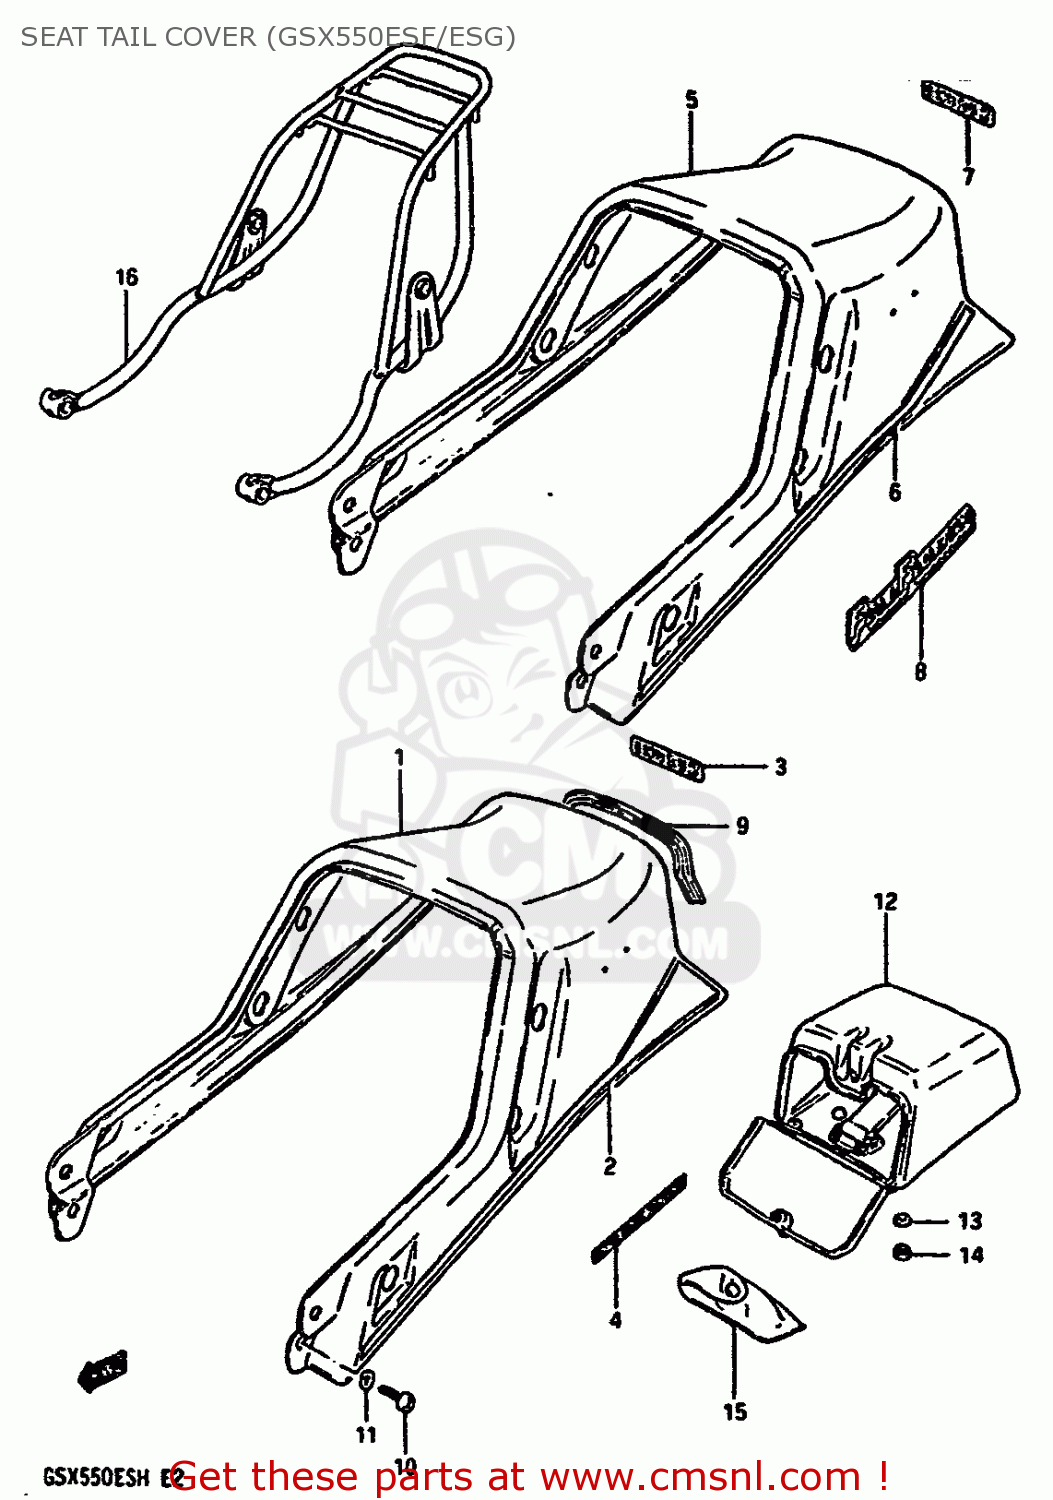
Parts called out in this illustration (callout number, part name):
1	COVER,SEAT TAIL
2	TAPE SET,SEAT TAIL COVER
3	EMBLEM (WHITE)
4	EMBLEM
5	SEAT TAIL COVE
6	TAPE SET
7	EMBLEM(WHITE)
8	EMBLEM
9	BLIND,SEAT TAIL COVER
10	SCREW
11	WASHER,LOCK
12	BOX,SEAT TAIL
13	WASHER
14	NUT
15	TOOL ASSY
16	CARRIER, SPORTS
